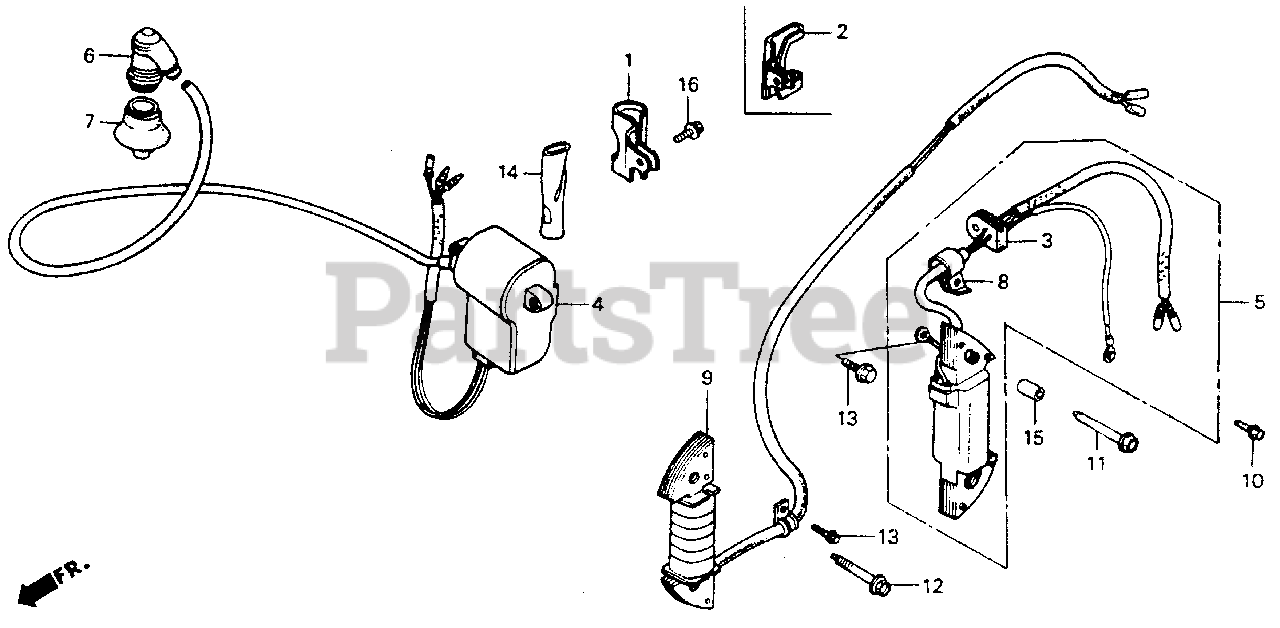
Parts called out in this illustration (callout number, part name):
1	CLIP, WIRE
3	GROMMET, WIRE
4	LAMP UNIT, C.D.I. (NOT AVAILABLE)
5	COIL ASSY., EXCITER (NOT AVAILABLE)
6	CAP ASSY., NOISE SUPPRESSOR
7	SEAL, IGNITION
8	CLAMP, IGNITION WIRE
9	COIL ASSY., CHARGE (SILICON RECTIFIER)
10	BOLT, FLANGE (6X12) (CT200)
11	BOLT, FLANGE (6X28)
12	BOLT, FLANGE (6X32)
13	BOLT, FLANGE (5X10)
14	TUBE, WIRE
15	PIN A, DOWEL (8X14)
16	BOLT, FLANGE (6X12)
